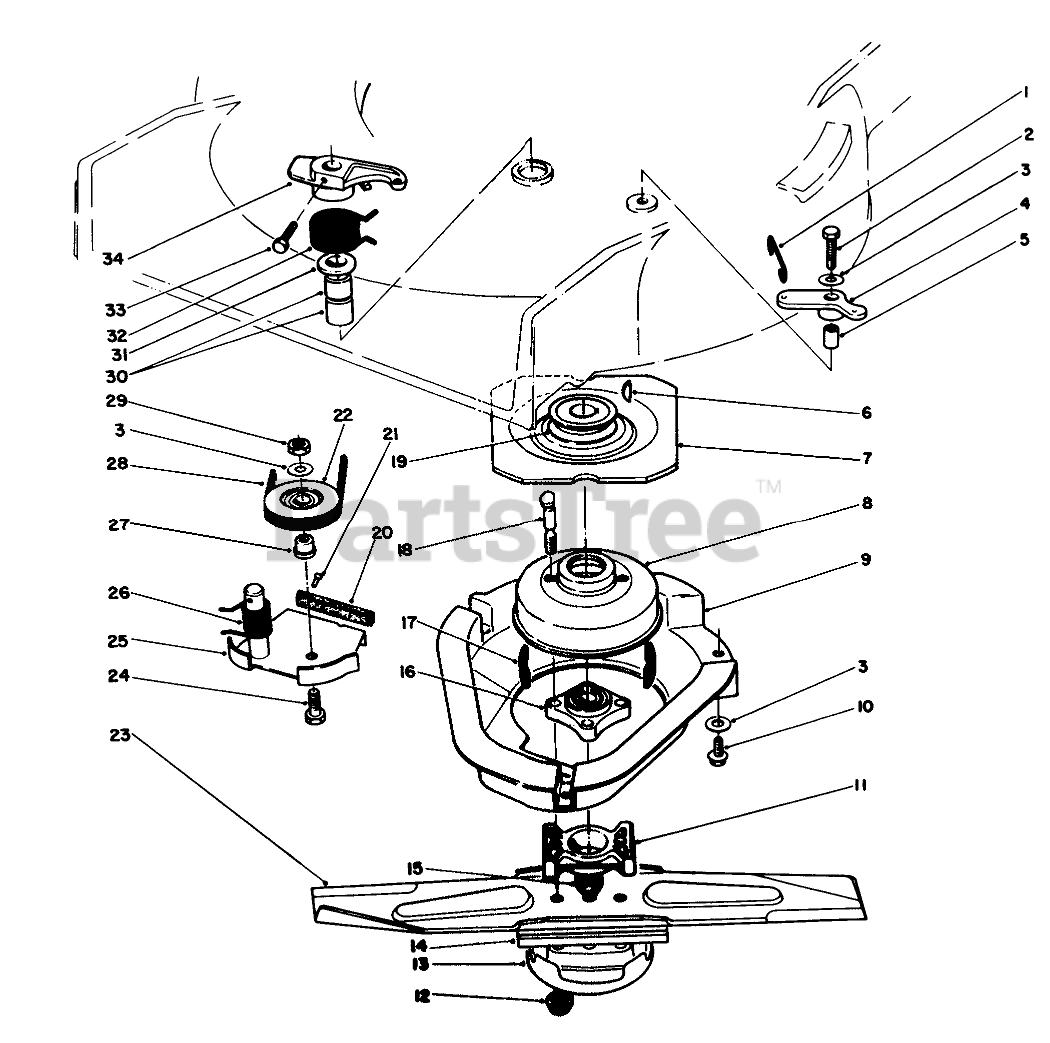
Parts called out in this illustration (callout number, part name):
1	LINK-CONTROL
2	SCREW-HH
3	WASHER-PLAIN
4	BELLCRANK
5	SLEEVE-BELLCRANK
6	KEY-WOODRUFF
7	Flywheel
8	Drum-Brake
9	SHIELD BBC
10	SCREW-HWHTF
11	SPACER-BLADE
12	NUT-LOCK
13	CUP-SCALP, ANTI
14	Stiffener
15	NUT-LOCK, NI
16	HUB ASM
17	DAMPENER-VIBRATION
18	BOLT-BLADE
19	PULLEY
20	Pad-Brake
21	.185 DIA X .375 RT +
22	PULLEY-IDLER
23	Blade-21" (Incl. Ref. #14)
24	SCREW-HH
25	Brake Plate (Incl. Ref. #20 & 21)
26	SPRING-TORSION
27	HUB-PULLEY, IDLER
28	V-BELT
29	NUT-LOCK, NI
30	BEARING
31	WASHER
32	SPRING-TORSION
33	SCREW-HH
34	LEVER
